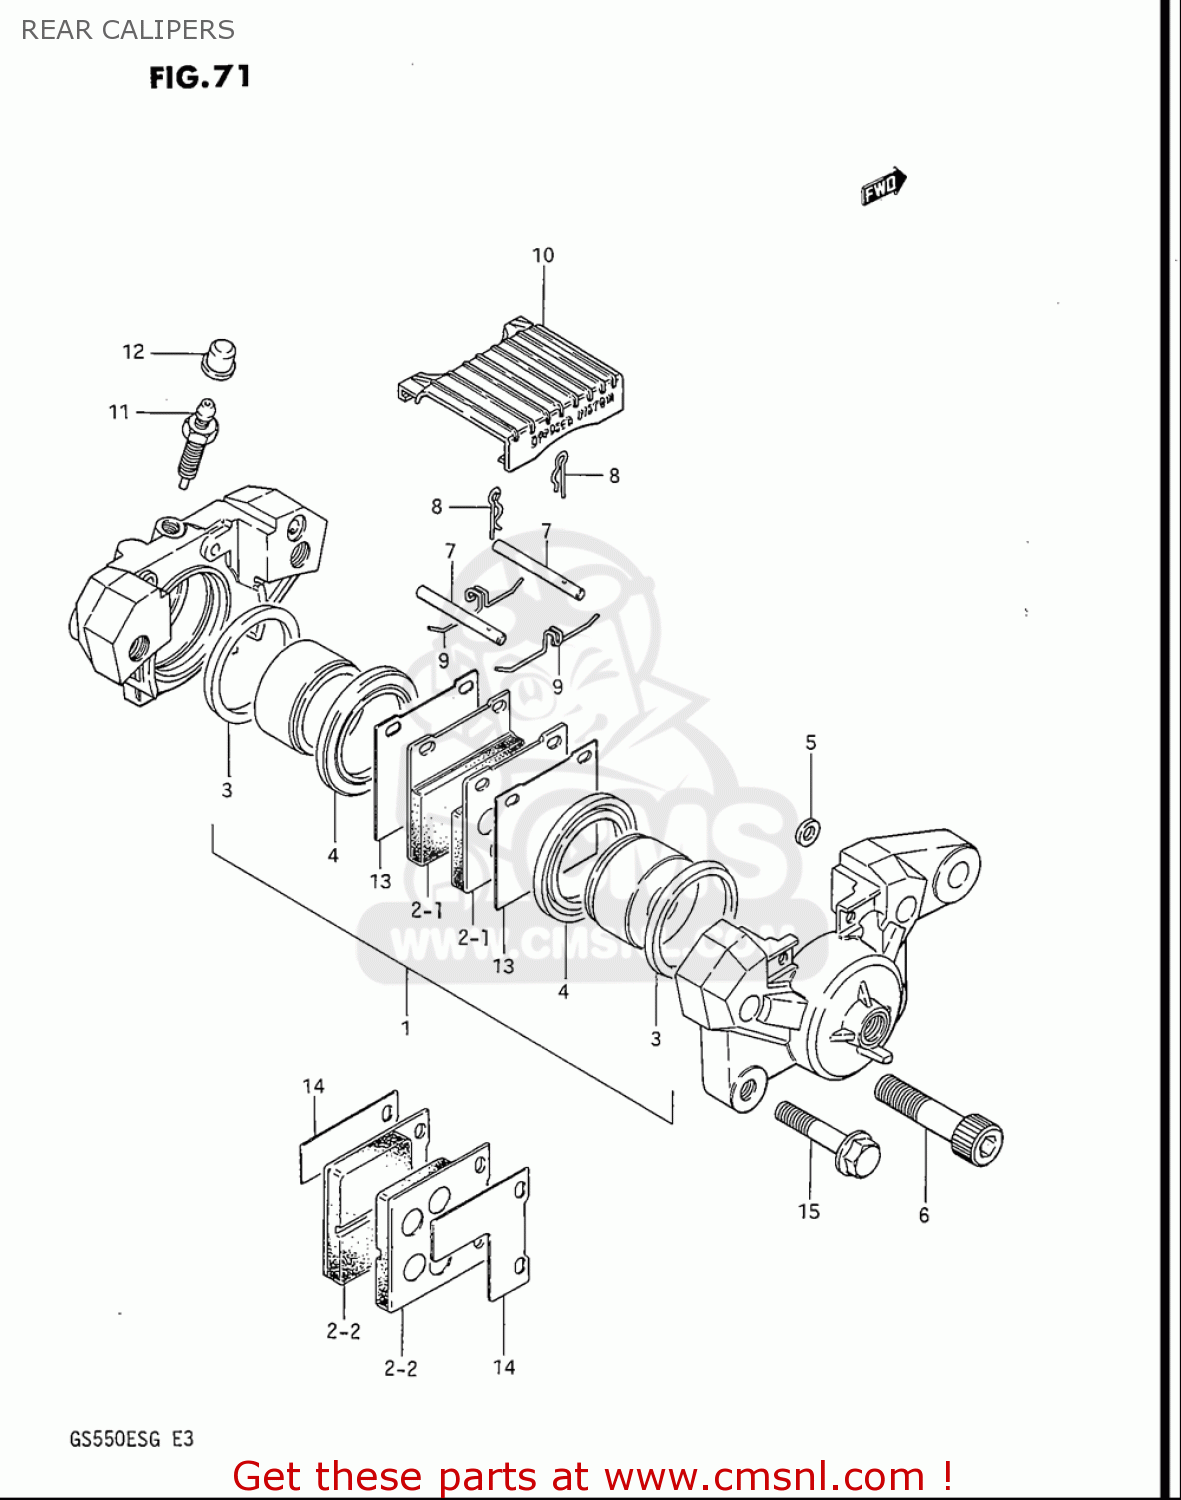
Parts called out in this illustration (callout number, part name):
1	PISTON SET
2	PAD SET
3	SEAL,PISTON
4	BOOT
5	SEAL,JOINT
6	BOLT,HOUSING
7	PIN,PAD
8	CLIP,PAD PIN
9	SPRING
10	COVER
11	BLEEDER
12	CAP,BLEEDER PLUG
13	SHIM,PAD
14	SHIM
15	BOLT
